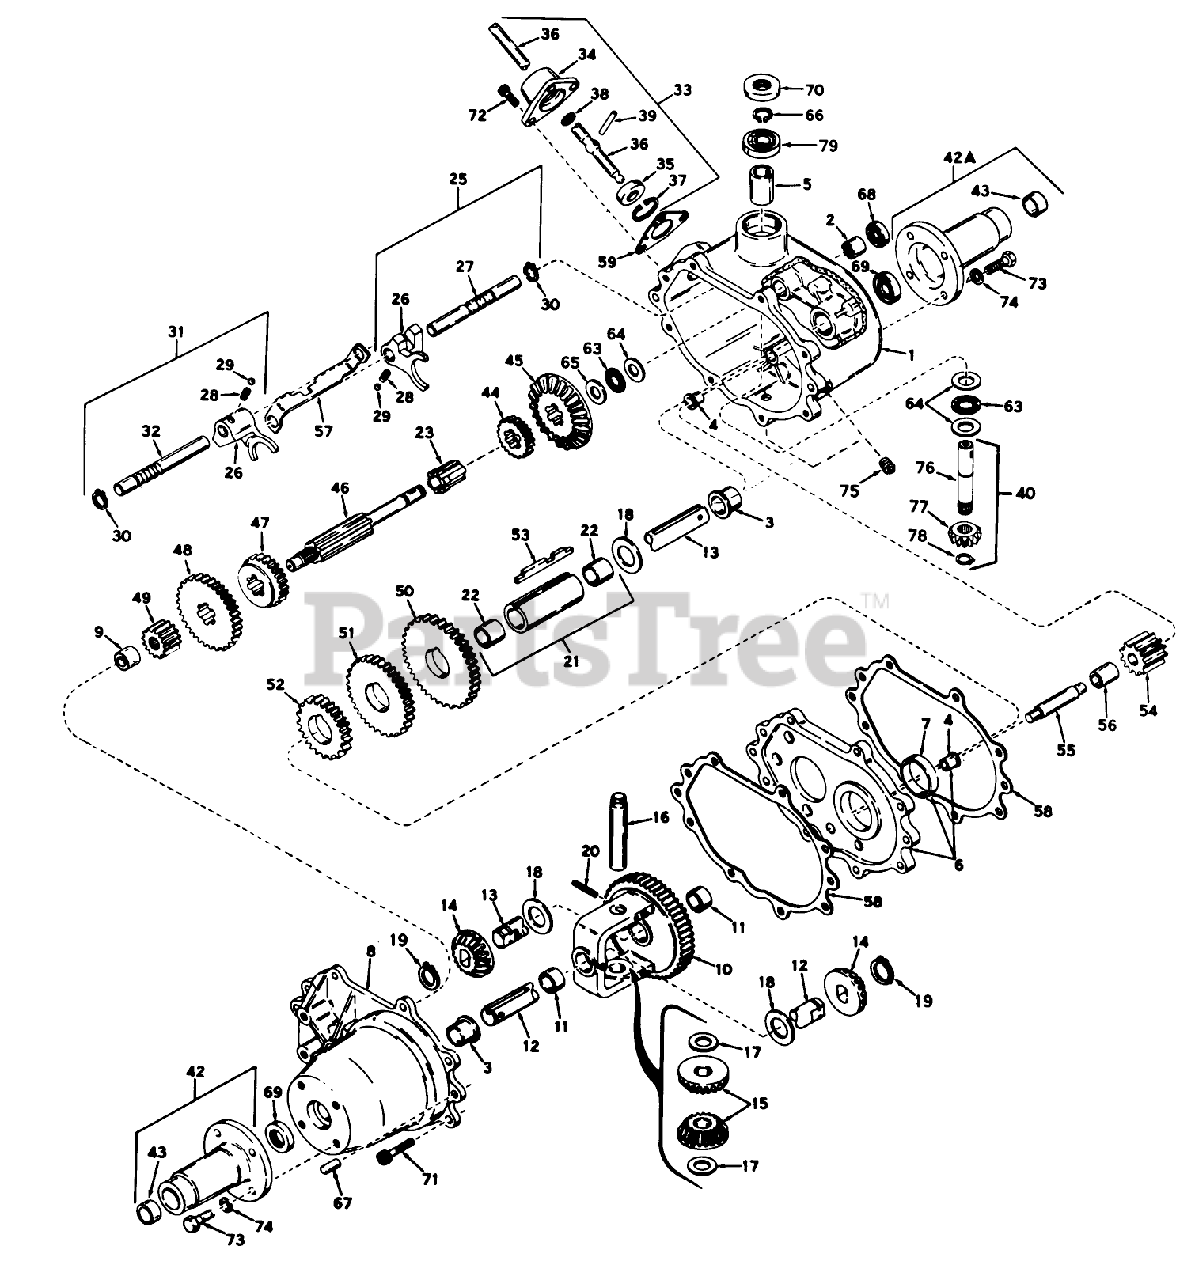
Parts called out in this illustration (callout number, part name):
1	Case Assy., Transaxle (Incl. Nos. 2 thru 5)
2	Bearing-Needle
3	Bronze Bearing
4	Bronze Bearing
5	Bronze Bearing
6	Plate Assy., Center (Incl. Nos. 4 7)
7	Bronze Bearing
8	Cover Assy., Transaxle (Incl.Nos. 3 9)
9	Needle Bearing
10	Gear Assy., Differential (Incl. No. 11)
11	Bushing
12	Axle, Left Hand
13	Axle, Left Hand
14	Bevel Gear
15	Gear Pinion
16	Drive Pin
17	Thrust Washer
18	Washer
19	Snap Ring
20	Pin-Roll
21	Countershaft Sleeve Assy (Incl. No. 22)
22	Bronze Bearing
23	Shaft, Idler
25	Shift Rod Assy (1st and Rev.)(Incl. Nos. 26 thru 30)
26	Shift Fork
27	Shift Rod
28	Spring
29	Piston ASM
30	Ring-Snap
31	Shift Rod Assy (2nd 3rd)(Incl. No. 26, 28, 29, 30, and 32)
32	Shift Rod
33	Lever Housing Assy., Shift (Incl. Nos. 34 thru 39)
34	Shift Lever Housing
35	Keeper-Shift Lever
36	Lever, Shift
37	Ring-Snap
38	O Ring
39	Roll Pin
40	Shaft Gear Assy., Input (Incl. Nos. 76, 77 78)
42	Housing Assy., Axle (Incl. No. 43)
42A	Housing Assy., Axle (Incl. No. 43)
43	O Ring
44	Gear (10 teeth)
45	Bevel Gear (33 teeth)
46	Shaft, Shifter Brake
47	Gear, Shifting (2nd 3rd)
48	Gear, Shifting (1st Rev.)
49	Spur Gear (12 teeth)
50	Countershaft Drive Gear (39 teeth)
51	Gear (34 teeth)
52	Countershaft Gear (25 teeth)
53	Key, Countershaft
54	Reverse Idler
55	Reverse Idler Shaft
56	Reverse Idler Spacer
57	Shifter Stop
58	Gasket, Case Cover
59	Shift Lever Housing Gasket
63	Bearing-Thrust
64	Washer
65	Washer, Thrust
66	Ring-Snap
67	Dowel Pin
68	Seal, Oil
69	Oil Seal
70	Oil Seal
71	Ring-Retaining
72	Screw, Socket Hd. Cap
73	Screw-Hex Hd.
74	Lockwasher
75	Plug-Pipe
76	Shaft, Input
77	Pinion, Input
78	Ring-Retainer
79	Bearing, Ball
